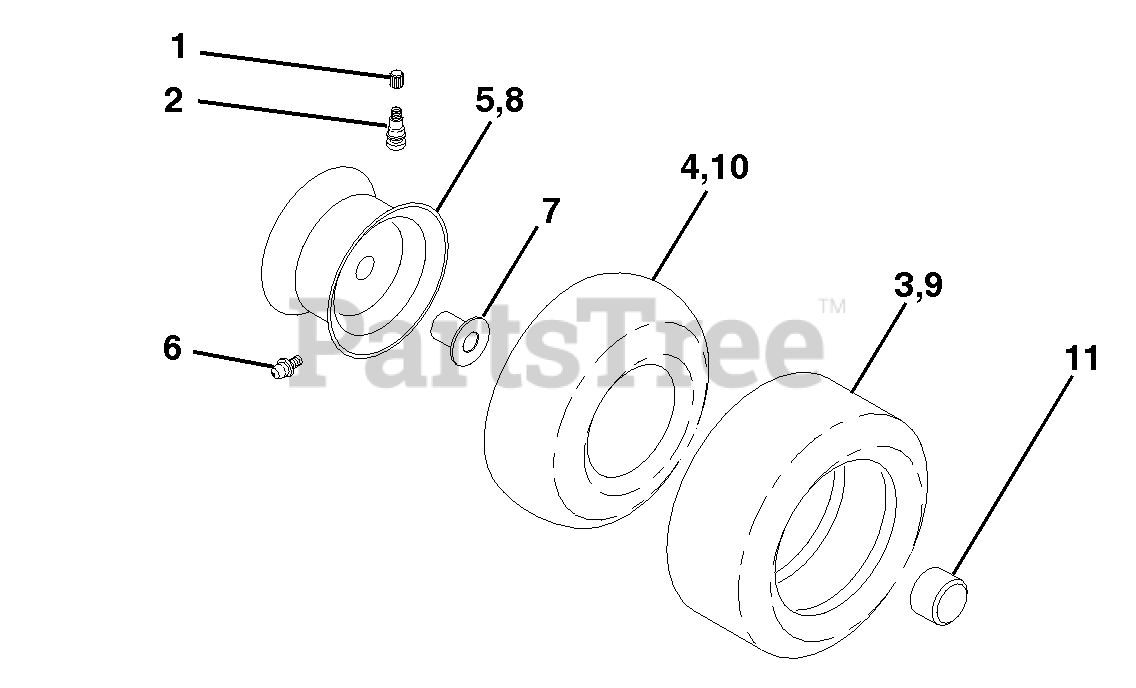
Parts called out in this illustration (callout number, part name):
1	Cap Valve Tire
2	Stem Valve
3	Tire F Ts 15 X 6 0 - 6
4	Tube Front
5	Rim Asm 6" front Silver
6	Fitting Grease
7	Bearing Flange
8	Rim Asm 8" rear Silver
9	Tire R Ts 18 x 8 5-8 C
10	Tube Rear
11	Cap Axle Blk 1 50 X 1 00
